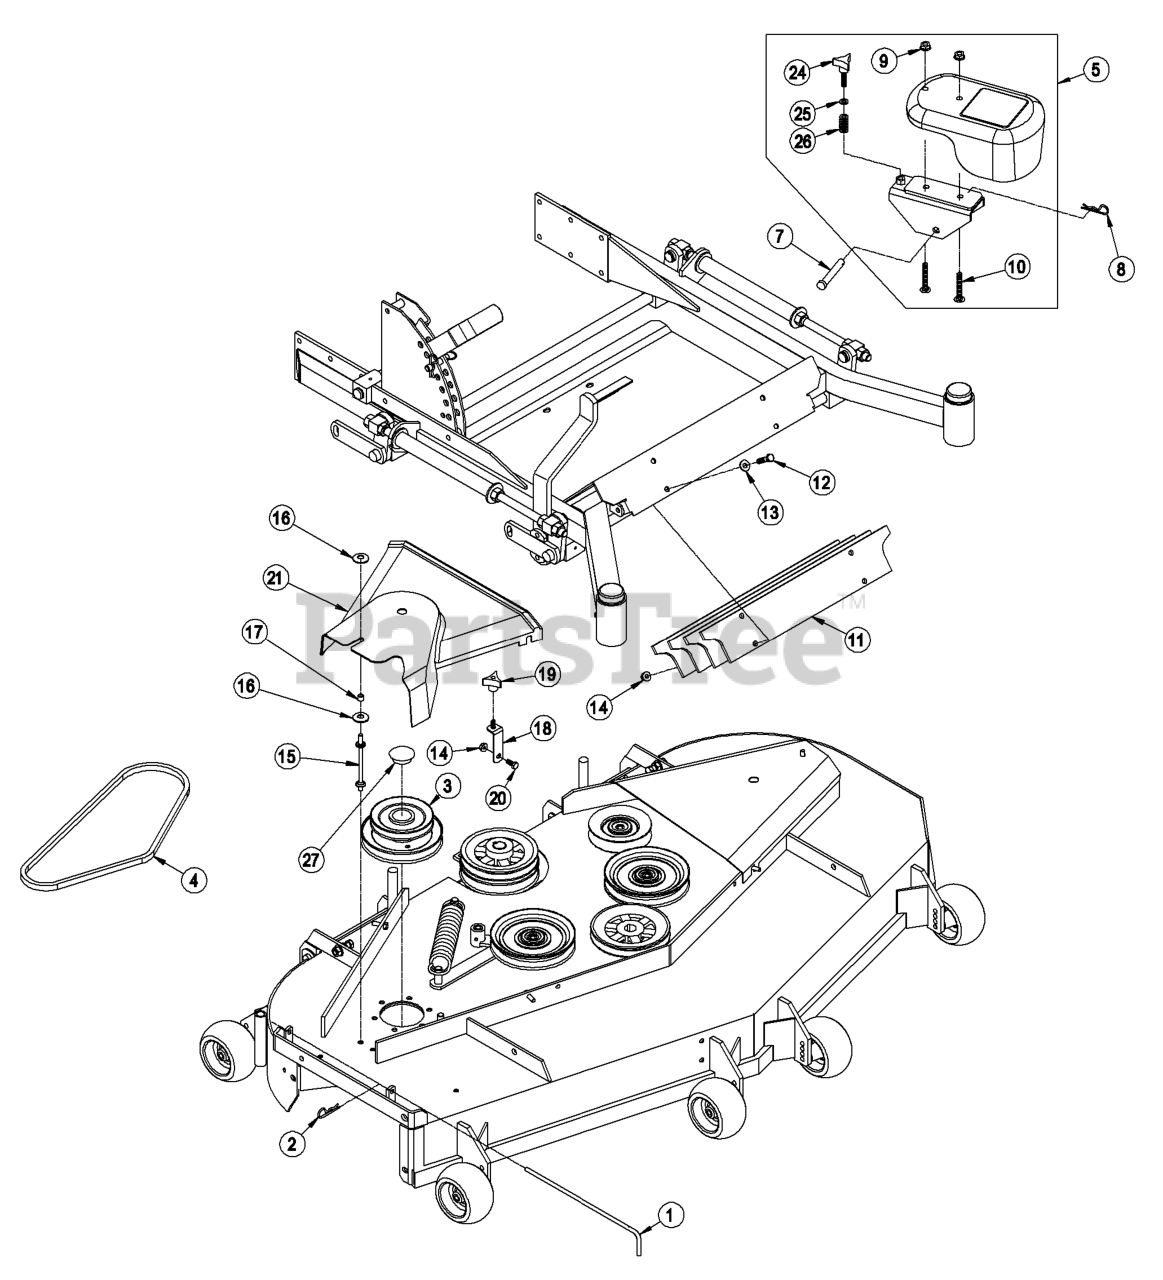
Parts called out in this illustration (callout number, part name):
1	PIN, CHUTE PIVOT
2	PIN-COTTER
3	JACKSHAFT, LZUV 60
4	BELT, BLOWER DRIVE 60
5	ASM, WEIGHT 1.5" 70 POUND
5	ASM, WEIGHT 2.0" 70 POUND
6	WLD, BRACKET 2.0 ARM
6	WLD, BRACKET 1.5 ARM
7	PIN-CLEVIS
8	PIN-COTTER
9	NUT-HHF, WHIZ
10	BOLT, SQUARE HEAD YZ
12	SCREW-HH
13	WASHER-PLAIN
15	STUD,BELT SHIELD 4 INCH
16	WASHER-SPRING
18	Support, Belt Cover
19	Knob
21	COVER, BELT 60
25	WASHER-FLAT
27	PLUG, BLACK NYLON 1.75
